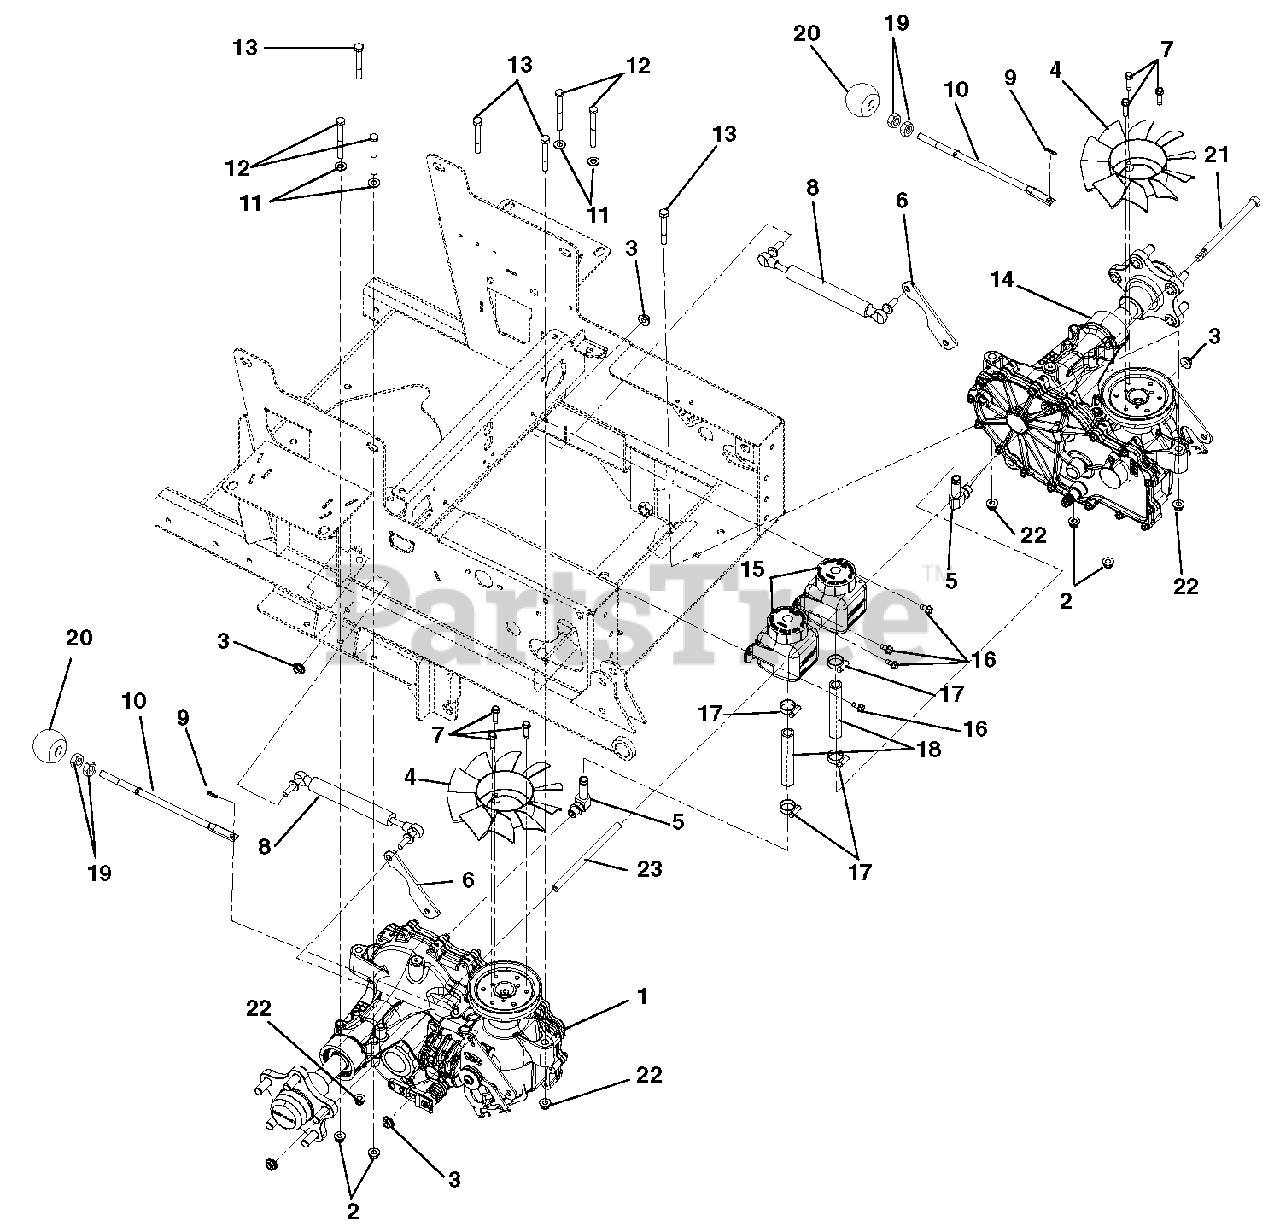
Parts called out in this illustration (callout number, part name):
1	TRANSAXLE, RH 3400
2	@NUT-LK-NYL-FLG .31-18 YWZC
3	NUT, FLG PATCH M8-1.25 BLKZC
4	FAN, 2800 SERIES COOLING
5	FITTING, HYD (90 DEG)
6	PLATE, CONTROL REINFORCEMENT
7	@SCR-TAP .25-20X1.00 HWH TR YZ
9	PIN-HAIR INT .06X.18X.77
10	LEVER, PT100 DUMP VALVE
11	@WSHR-FL-STL.344X.688X.065YWZC
12	@BLT-HEX .31-18X3.00 GR5 YWZC
13	@BLT-HEX .38-16X2.50 GR5 YWZC
14	TRANSAXLE, LH 3400
15	TANK, EXPANSION
16	SCR-TAP .25-20X.50 HWH TR YWZ
17	CLAMP,.88 DIA. HOSE
18	HOSE, 100I HYDRO OVERFLOW
19	NUT- JAM .312-18 YWZC
20	KNOB-BALL-BLACK .312-18 X 1.00
21	BLT HEX, .38-16X11.00 GR5 YWZC
22	@NUT-LK-NYL-FLG .38-16 YWZC
23	SPCR,.406 ID X .630 OD X 7.724
